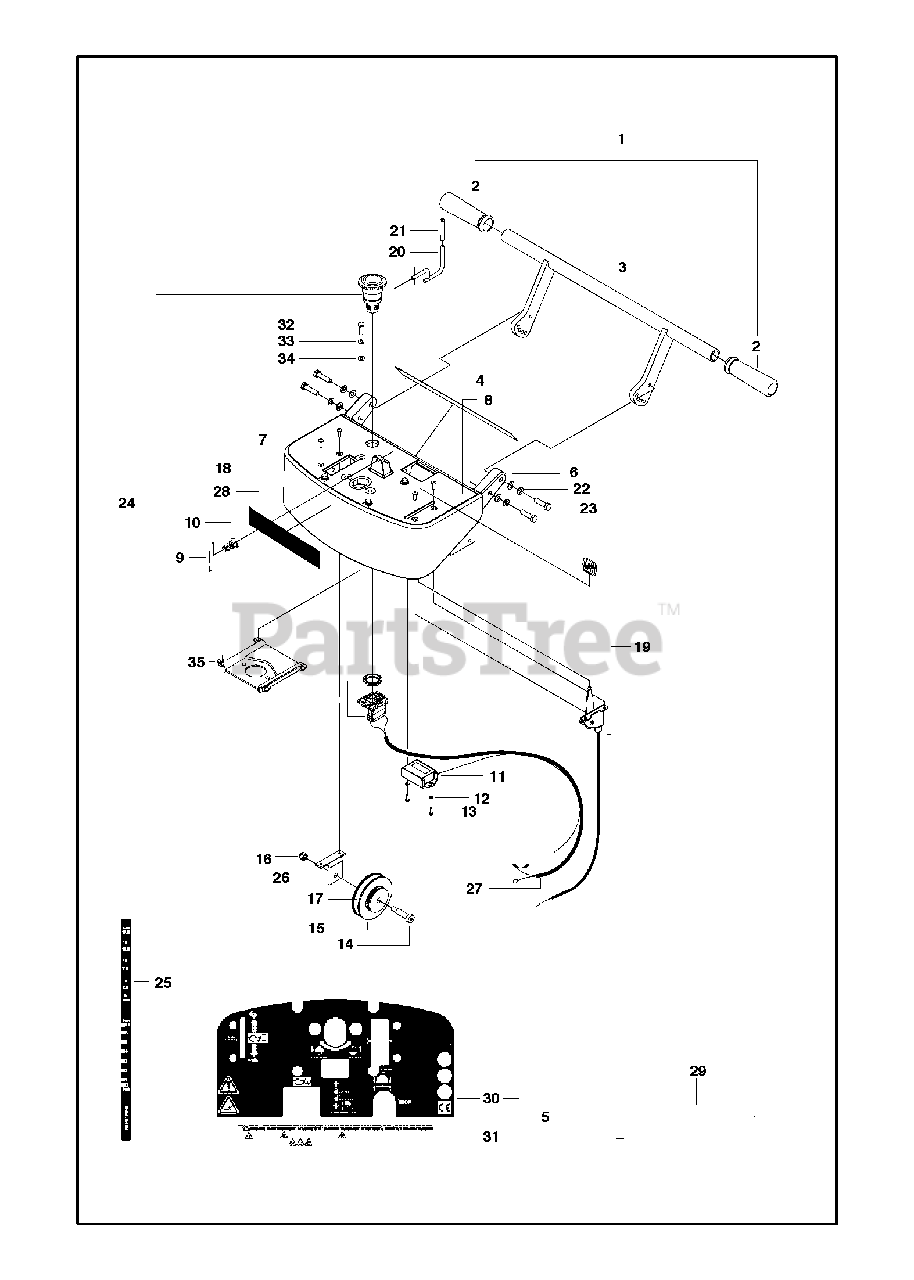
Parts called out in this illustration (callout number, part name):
6	WASHER
12	SPRING WASHER 4.1X7.1
16	HEXAGON LOCKING NUT
22	SPRING WASHER
